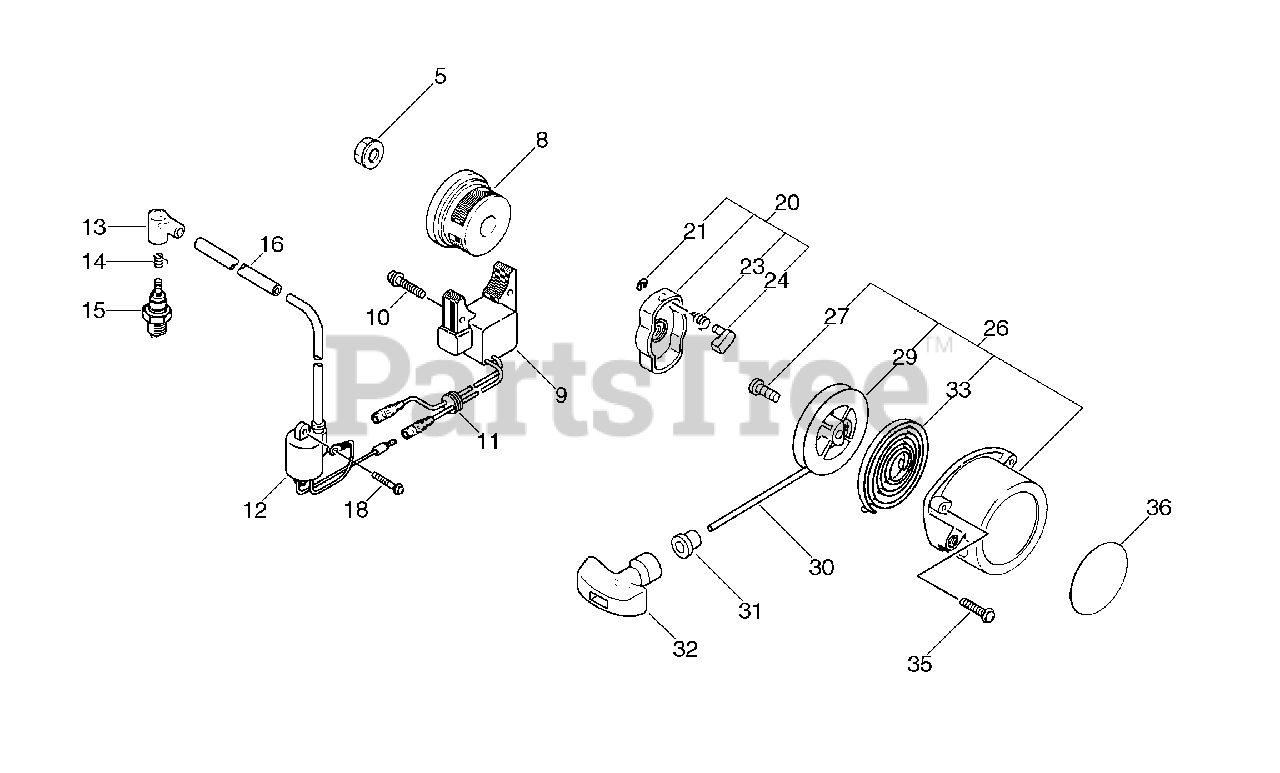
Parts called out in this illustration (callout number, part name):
5	NUT - 10 -- FLANGE
8	FLYWHEEL
9	COIL, IGNITION
10	SCREW - 5X25
12	COIL, IGNITION
13	CAP, SPARK PLUG
14	TERMINAL, SPARK PLUG CAP
15	SPARK PLUG -- BM-6A
18	SCREW - 4X16
20	STARTER PAWL ASSY
21	RING, RETAINING - 4
23	SPRING, RETURN
24	PAWL, STARTER
26	STARTER ASSY
29	REEL, ROPE
30	ROPE, STARTER - 4X880
31	GUIDE, ROPE
32	GRIP, STARTER
33	SPRING, REWIND
35	SCREW - 5X18
36	LABEL - ECHO
